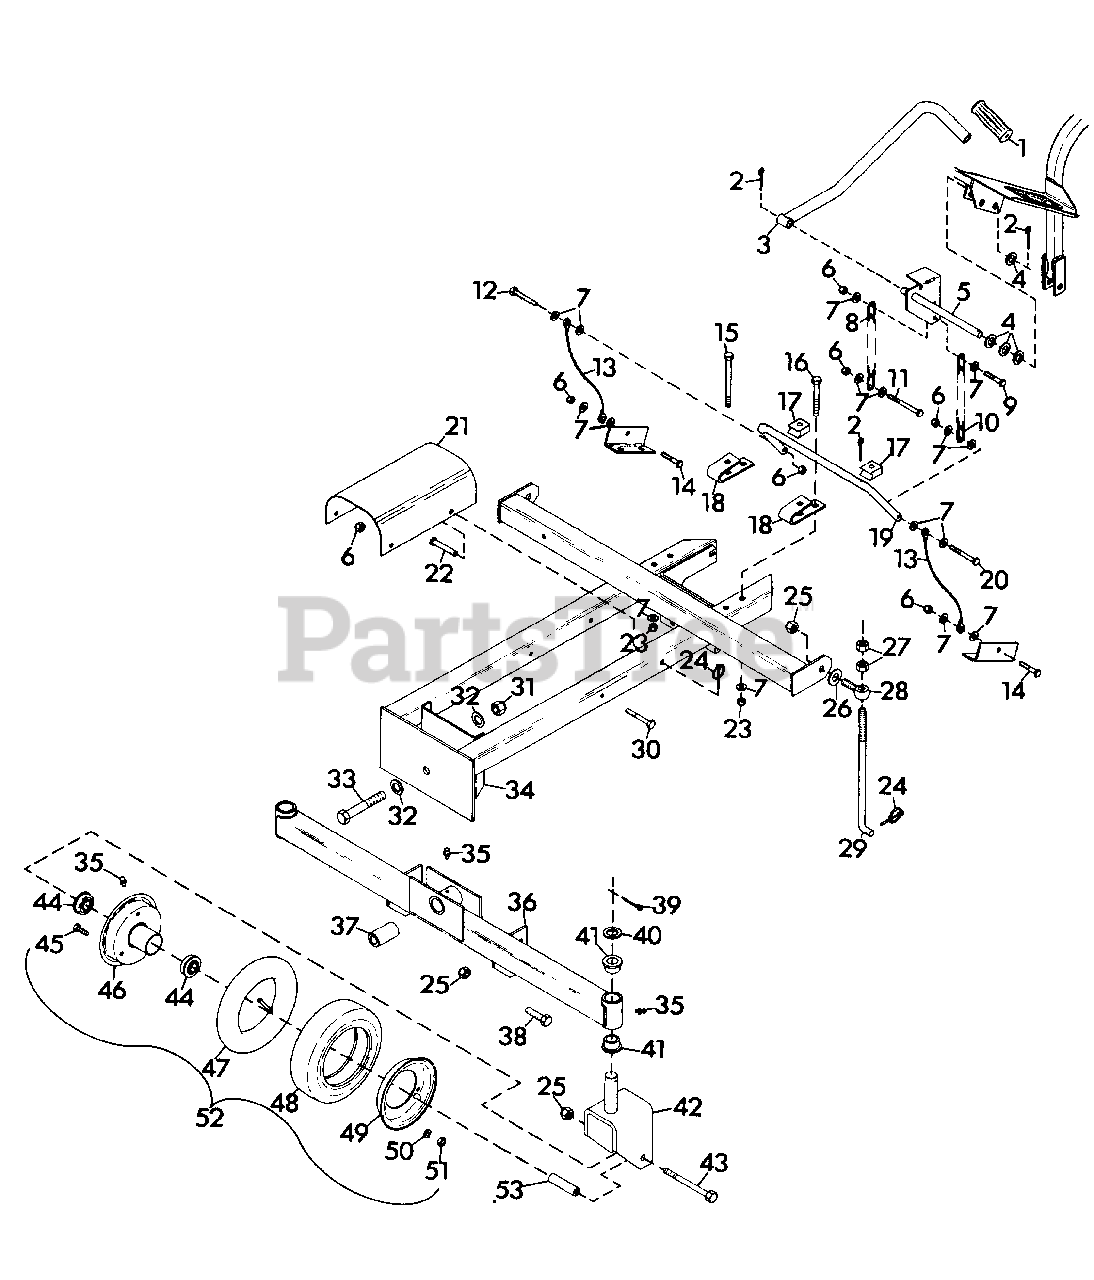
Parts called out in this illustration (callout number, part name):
1	GRIP
2	PIN, COTTER .12X1.25
3	WELDMENT, LIFT LEVER
4	WASHER, FLAT .656X1.250X.100
5	WELDMENT, LIFT BRACKET
6	NUT, LOCK 5/16-18
7	WASHER, FLAT .406X.812X.065
8	CHAIN, LIFT(8 LINKS)
9	BOLT, HEX 5/16-18X1.25
10	CHAIN, LIFT(7 LINKS)
11	BOLT, HEX 5/16-18X3.25
12	BOLT, HEX 5/16-18X1.75
13	CABLE, LIFT
14	BOLT, HEX 5/16-18X1.00
15	BOLT, HEX 3/8-16X4.00
16	BOLT, HEX 3/8-16X3.00
17	STOP, NYLON
18	BRACKET, AXLE SUPPORT
19	ARM, PIVOT
20	BOLT, HEX 5/16-18X2.00
21	GUARD, PTO SHAFT
22	PIN, CLEVIS
23	NUT, LOCK 3/8-16
24	PIN, KLIK
25	NUT, LOCK 1/2-13
26	WASHER, FLAT .500X1.250X.083
27	NUT, JAM 1/2-13 HEX
28	BOLT, EYE
29	ROD, HEIGHT ADJUSTMENT
30	BOLT, HEX 5/16-18X2.50
31	NUT, LOCK 3/4-10
32	WASHER, FLAT .812X1.469X.130
33	BOLT, HEX 3/4-10X4.50
34	WELDMENT, MOWER FRAME
35	FITTING, LUBE 1/4-28
36	AXLE
37	TUBE, PIVOT
38	BOLT, HEX 1/2-13X1.375
39	PIN, COTTER .187X1.625
40	RACE, BEARING THRUST
41	BUSHING, PIVOT
42	WELDMENT, CASTER FORK
43	BOLT, HEX 1/2-13X5.00
44	BEARING, GAUGE WHEEL
45	BOLT, HEX 3/8-24X.75
46	WHEEL, HALF WITH HUB
47	TUBE, INNER
48	TIRE, GAUGE WHEEL
49	WHEEL, HALF PLAIN
50	WASHER, LOCK 3/8 SP HEAVY
51	NUT, HEX 3/8-24
52	WHEEL, GAUGE
53	BUSHING, WHEEL
